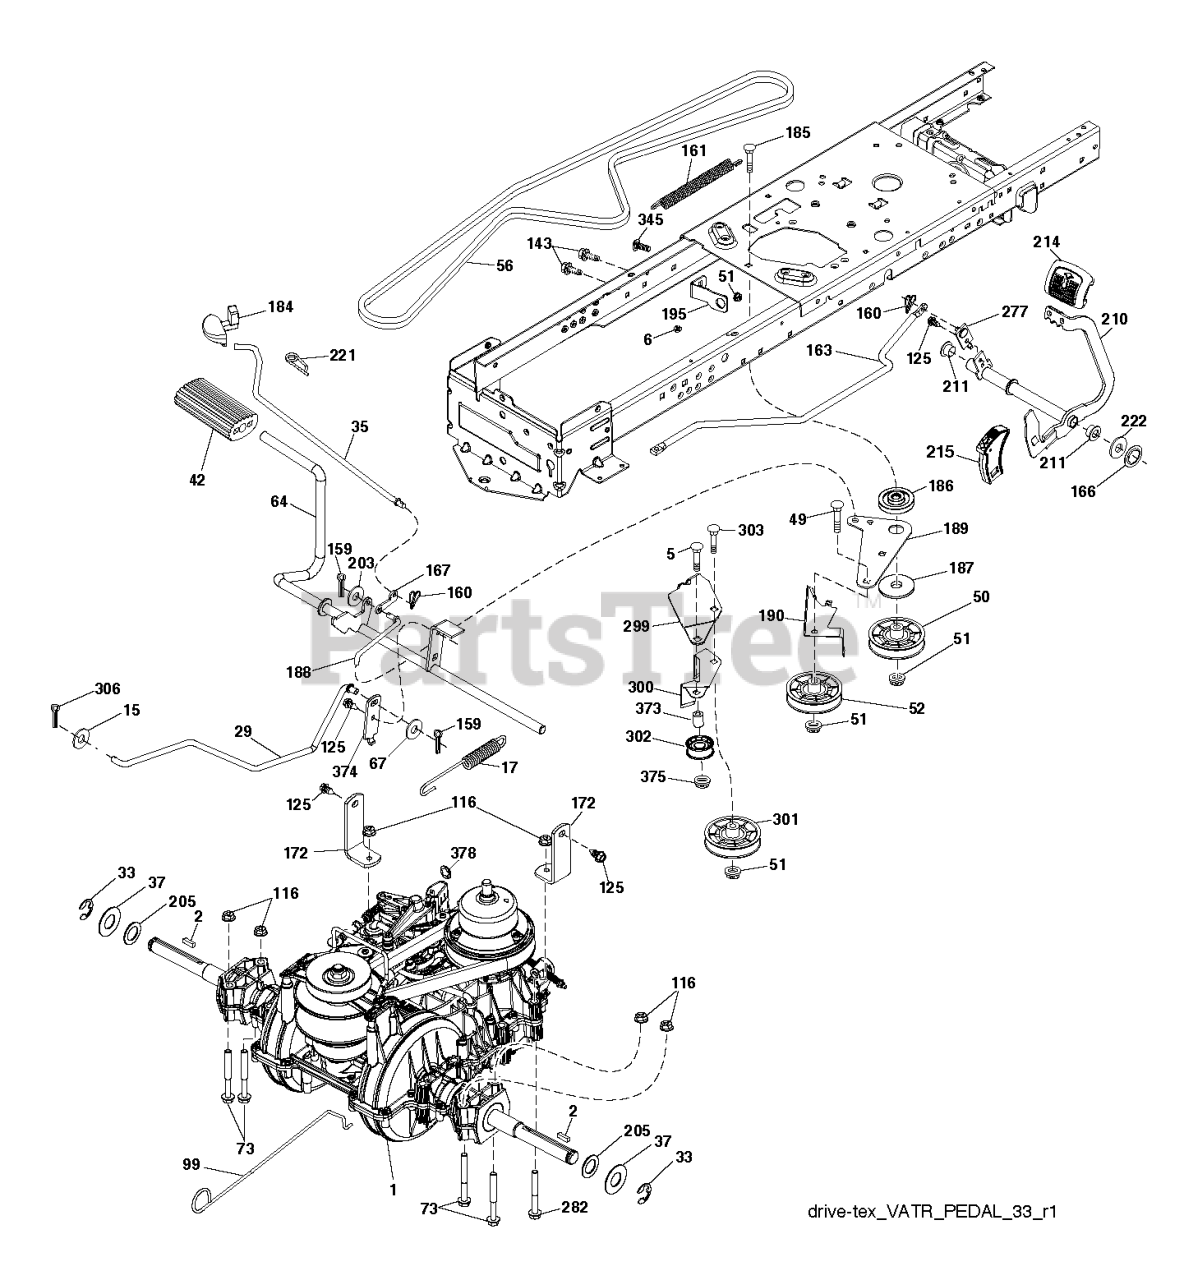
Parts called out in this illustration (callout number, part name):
2	Key, Square 2.5 x .1845/.1865 (AYP part number)
5	Bolt, Hex 3/8-16 UNC x 2-1/4 (AYP part number)
6	Bushing Snap Nyl Blk Fuel Line
15	Washer 13/32 x 1-3/16 x 12 Gauge (AYP part number)
17	SPRING.BRAKE.VARIATOR
29	ROD.BRAKE.VARIATOR.SD3.X431
33	E-ring #5133-75 (AYP part number)
35	ROD ROD.PARKINGBRAKE.GT.HUSQ/P
37	WASHER.HARDENED
42	Cover Pedal Blk Round (AYP part number)
49	Bolt, Carriage 3/8-16 x 1-3/4 Grade 5 (AYP part number)
50	IDLER.FLAT.910.OFFSET
51	NUT LOCK FLG 3/8-16 UNC
52	IDLER.V-GROOVE.910.OFFSET
56	BELT.DRIVE.MOWER.TEX.42"
64	SHAFT VARIATOR PEDAL CROSS
67	WASHER.NYLON;13/32X13/16X.109
73	BOLT HEX 5/16-18 GR 5
99	ROD.BYPASS.VARIATOR.GEN2
116	NUT LOCK HEX FLANGE 5/16-18
125	SCREW
143	SCR 5/16-18 X 1/2 SELFTAP ZN
159	Pin Cotter 1/8 x 3/4 CAD. (AYP part number)
160	RETAINER CLIP
161	X Spring Return Clutch 6 75 (AYP part number)
163	ROD.CONTROL.PEDAL.VARIATOR
166	NUT.PUSH.625
167	LATCH.BRAKE.SPRING
172	STRAP.TORQUE.VARIATOR
184	HANDLE.PARKING.BRAKE.H (BLK)
185	Bolt, Carriage 3/8 - 16 x 2-3/4 (AYP part number)
186	SPACER.RETAINER
187	Washer 12/32 x 2 x 10 Gauge (AYP part number)
188	LINK.CLUTCH.GROUND DRIVE.LONG
189	BELLCRANK.GROUND.DRIVE.TEX.
190	KEEPER.BELLCRANK.DRIVE
195	BRACKET.BRAKE.BRAKE.VAR.SD
203	Washer, Nut Lock Hex w/Ins. 5/6-18 (AYP part number)
205	Washer 25/32 x 1-5/8 x 16 Gauge (AYP part number)
210	PEDAL.ASM.ROCKET.VARIATOR.LT
211	Bearing Nylon Blk 629 Id (AYP part number)
214	PEDAL.FORWARD.PAD.TEX
215	CAP.PEDAL.REVERSE.VARIATOR
221	RETAINER.SPRING.CLIP.H
222	WASHER 21/32 X 1-1/4 X 10 GA.
277	SUBASM.LINK.ROCKER.PEDAL
282	BOLT HEX FLGHD 5/16-18X3 GR. 5
299	BRACKET.MOUNT.IDLERS
300	KEEPER.IDLERS.REAR.VARIATOR
301	PULLEY.IDLER.V-GROOVE
302	PULLEY.IDLER.FLAT.2"
303	Bolt, Carriage 3/8-16 x 2 1/4 (AYP part number)
306	Pin Cotter 1/8 X 1 Cad (AYP part number)
345	Bolt Rdhd Sht Sqnk 3/8 - 16 x 3/4 (AYP part number)
373	SPACER.IDLER
374	ARM.CONTROL.BRAKE
375	Nut, Hex, Lock Hex w/wsh 3/8-16
378	NUT.FLG.NYLOCK.1/4-20.GR.G.ZY
